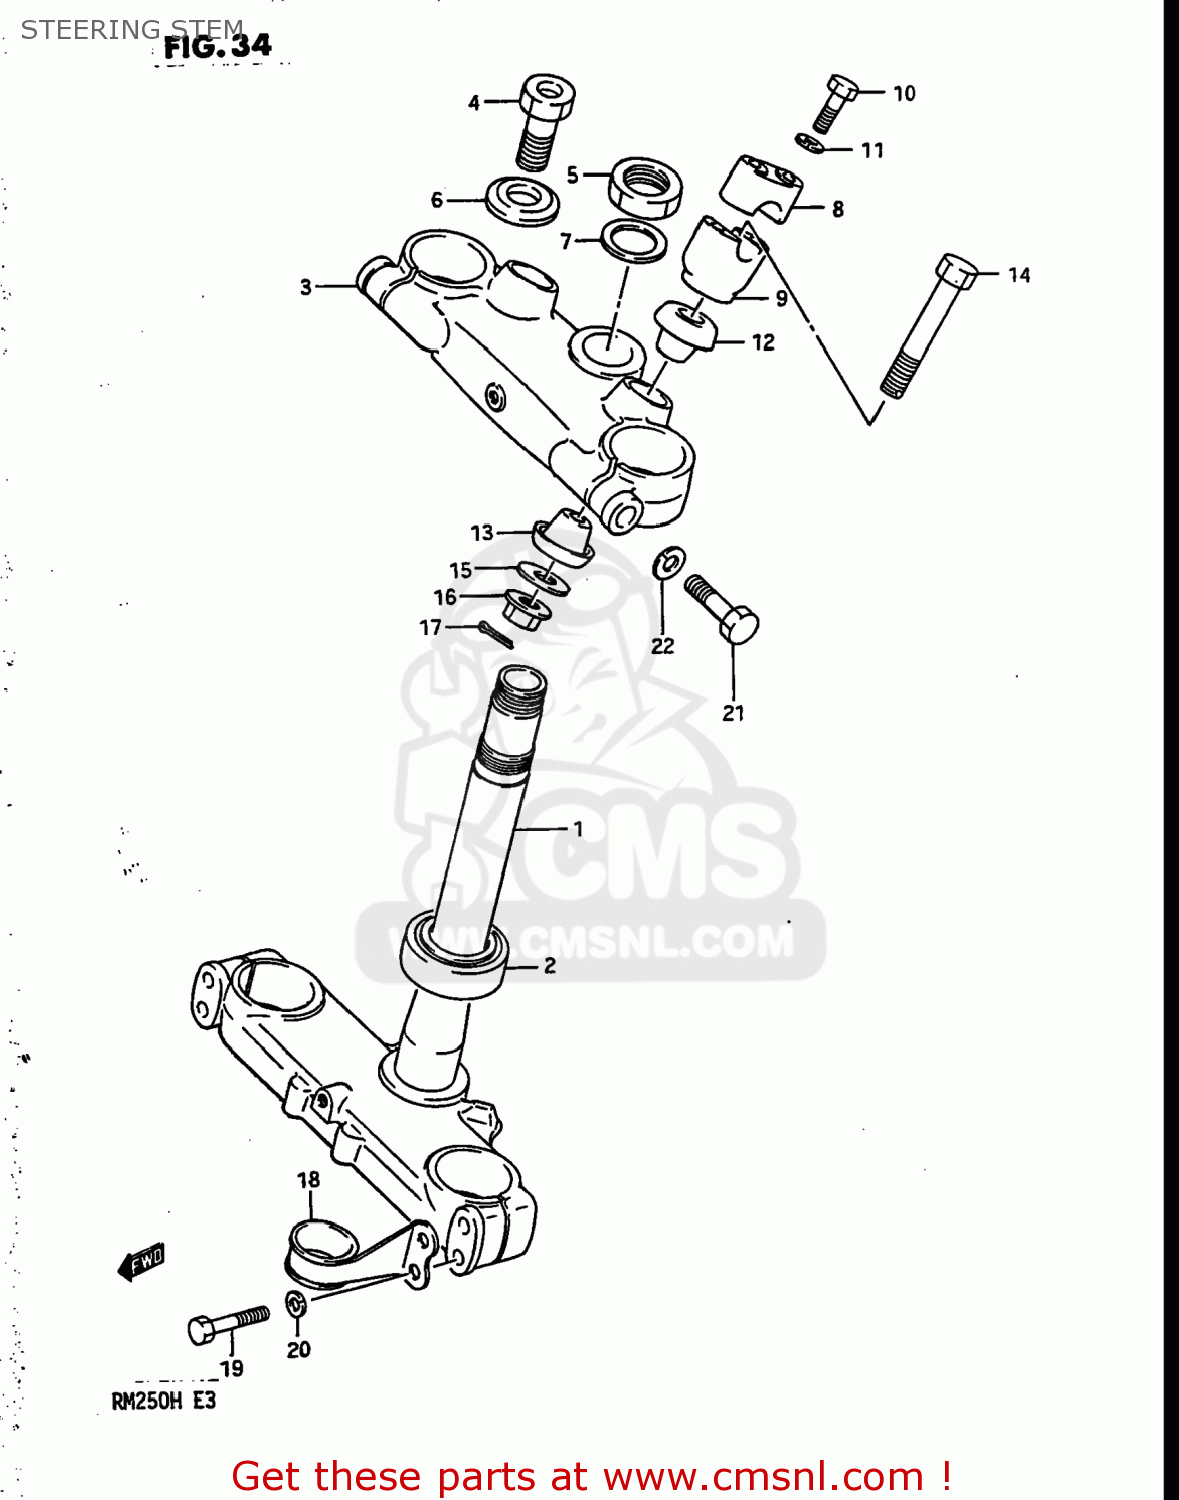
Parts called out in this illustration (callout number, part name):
1	STEM,STEERING
2	BEARING
3	HEAD,STEERING STEM
4	BOLT
5	NUT,STEERING STEM
6	WASHER
7	WASHER
8	HOLDER,HANDLEBAR
9	HOLDER,HANDLE LWR
10	BOLT
11	WASHER,LOCK
12	DAMPER,UPR
13	DAMPER,LWR
14	BOLT,HANDLE HOLDER
15	WASHER,HANDLEBAR HOLDER
16	NUT
17	COTTER PIN
18	CLIP
19	BOLT 8X40
20	WASHER,LOCK
21	BOLT
22	LOCK WASHER
